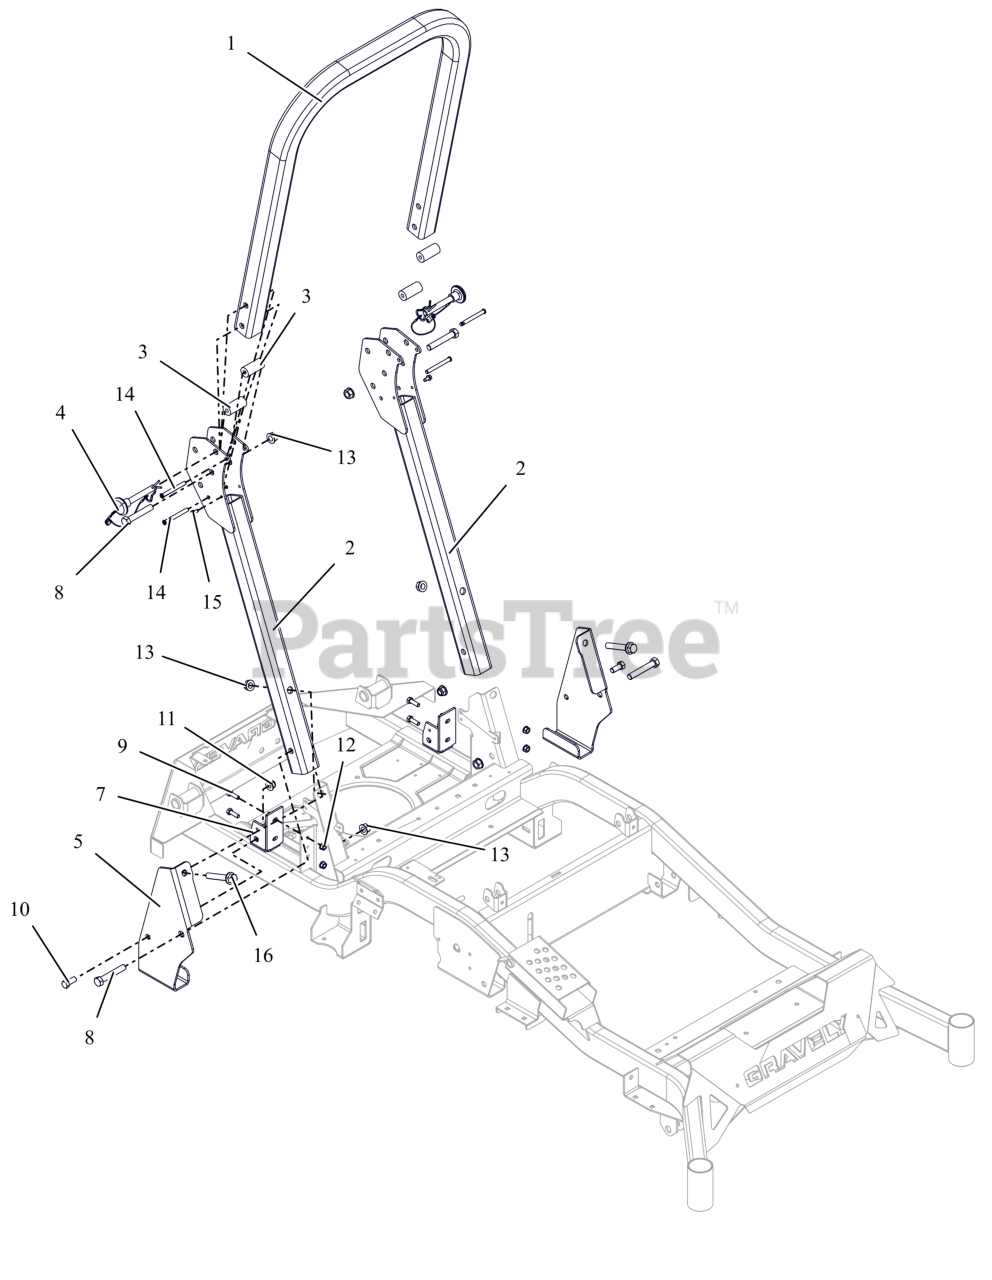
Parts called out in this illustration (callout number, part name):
1	HOOP, PT Z & ZX ROPS
2	ROPS,PROTURN Z REPLACEMENT-TALL
3	BUMPER, ROPS ANTI-VIBRATION
4	PIN, ROPS W/LANYARD
5	BRKT, ROPS SUPPORT - RH
6	BRKT, ROPS SUPPORT -LH
7	BRKT, ROPS SUPPORT
8	BLT, HEX .50-13X3.00 G5 ZCC
9	BLT, HEX .31-18X1.00 G8 ZCC
10	BLT, HEX 0.4375-14X1 GR5 ZCC
11	NUT,NYL-FLG .44-14 GF ZCC
12	NUT,LK-CTR-FLG .31-18 GF ZCC
13	NUT-LK-CTR-FLG .500-13 GG ZCC
14	PIN, SLIC .312 X 2.570
15	SCR-TAP .25-20X.50 HWH ZCC
16	BLT- HEX-FLG .50-13X3.00 G5 ZC
